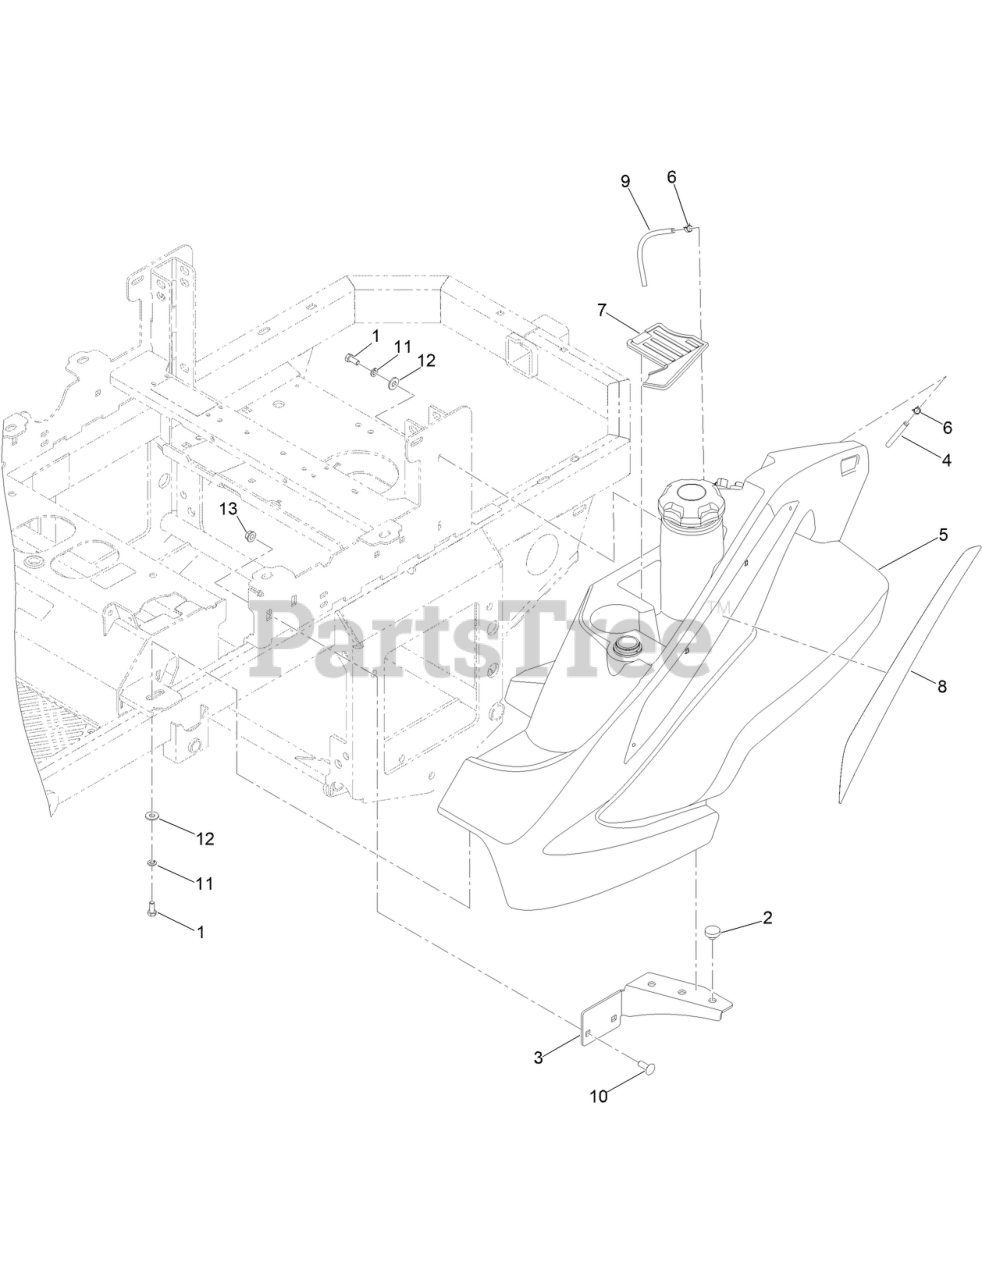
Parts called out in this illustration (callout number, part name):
1	SCREW-HH
2	PUSH-IN RUBBER BUMPER MWR FLOOR
3	RT/SRT GAS TANK SUPPORT PAINTED
4	MWR FUEL TANK BLACK 3/16IN VENT TUBE 1FT
5	MWR GASOLINE FUEL TANK ASSY
6	1/2IN (#8) HOSE CLAMP
7	RUBBER TANK STORAGE COMPARTMENT INSERT
8	DECAL-TANK
9	1/4IN SAE J30R7 BULK HOSE 1FT
10	3/8-16 X 1 CARRIAGE BOLT YZ GR.8
11	WASHER-LOCK
12	WASHER-FLAT
13	3/8-16 HEX FLANGE NUT W/SERR ZINC YELLOW
